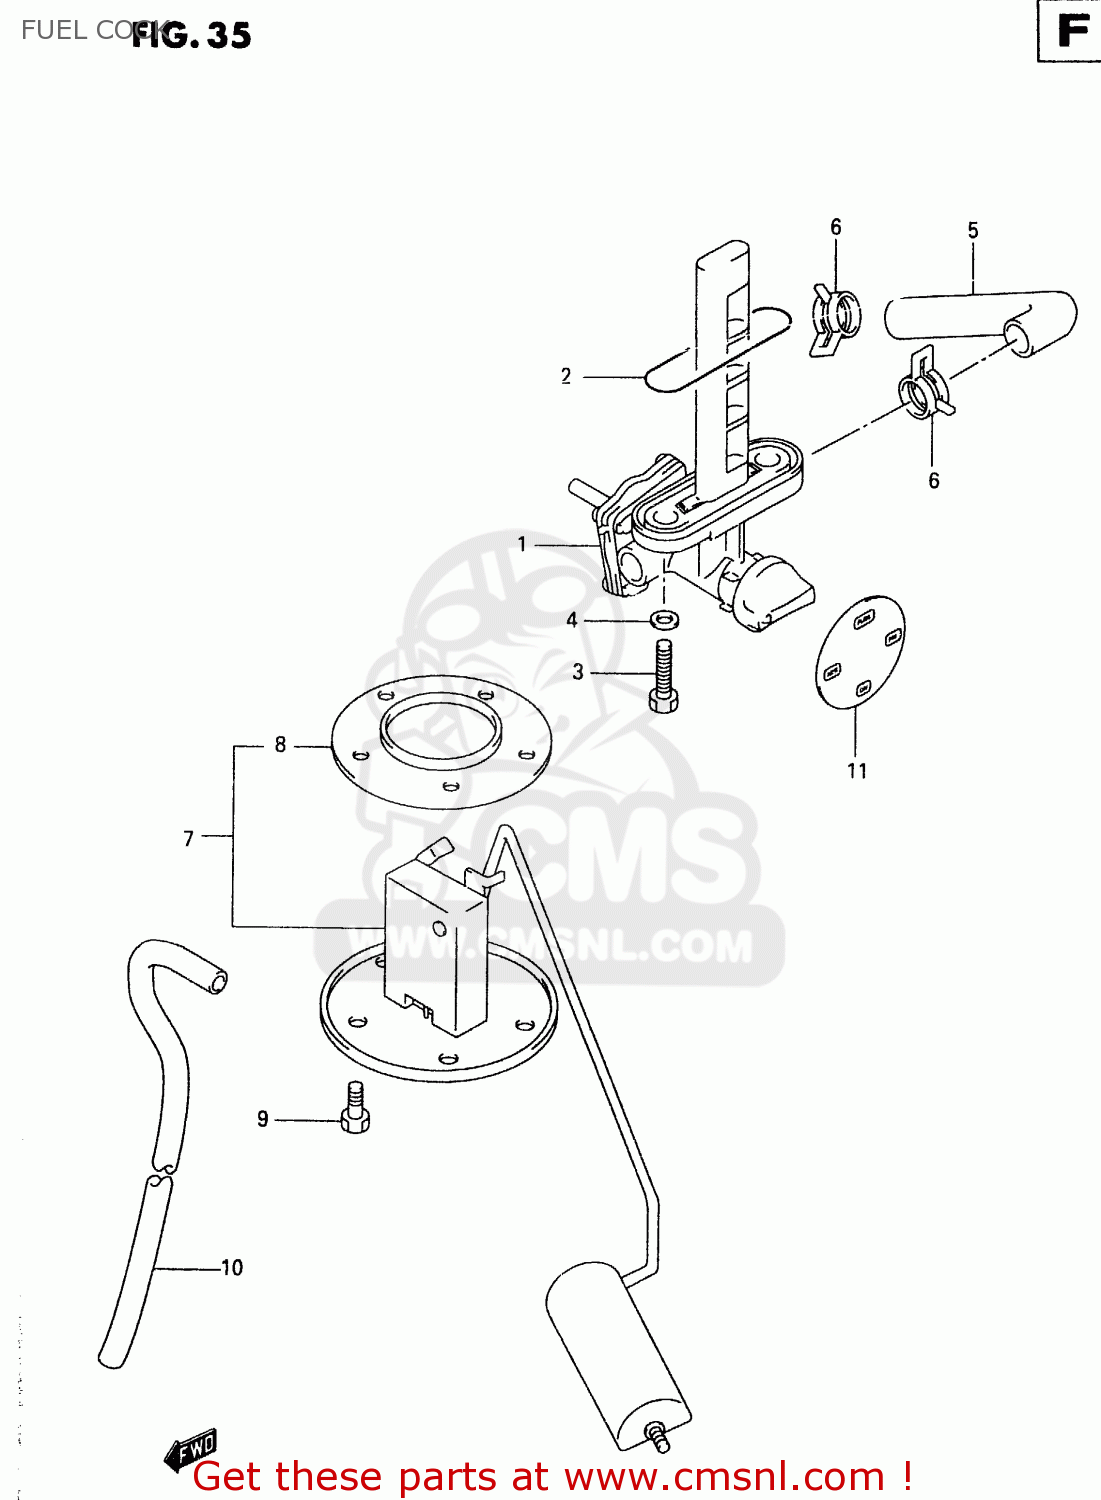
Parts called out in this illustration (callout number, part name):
1	COCK ASSEMBLY,FUEL
2	O RING
3	BOLT(6X20)
4	GASKET(6.4X11.5X0.8) (NAS)
5	HOSE,FUEL ON
6	CLIP
7	GAUGE ASSY,FUEL LEVEL SENDER
8	GASKET,FUEL LEVEL GAUGE (NAS)
9	BOLT 5X10
10	HOSE,FUEL TANK WATER DRAIN
11	LABEL,FUEL COCK(GRAY)
